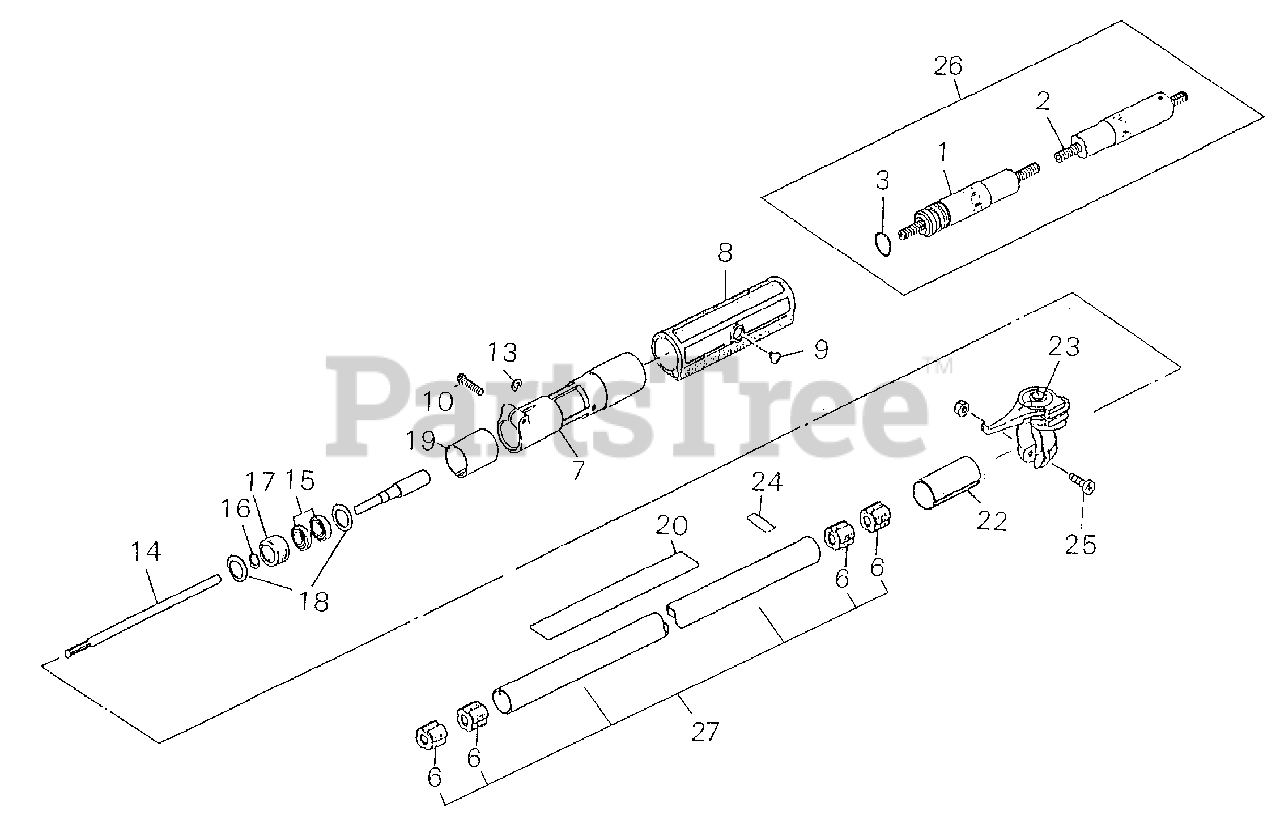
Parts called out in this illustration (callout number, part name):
1	TUBE, FLEXIBLE
2	DRIVESHAFT - FLEXIBLE
3	O-RING
6	BUSHING
7	CONNECTOR, PIPE
8	GRIP
9	SCREW
10	BOLT M6×28
14	MAINSHAFT
15	BEARING, BALL 6900
16	RING, SNAP Ø10
17	CUSHION
18	PLATE, THRUST
19	COLLAR
20	LABEL,CAUTION
22	SPACER
23	LEVER, THROTTLE
24	LABEL, HANDLE
25	SCREW M5×12
26	TUBE ASSY, FLEX
27	MAIN PIPE ASSY
29	LABEL, CAUTION
